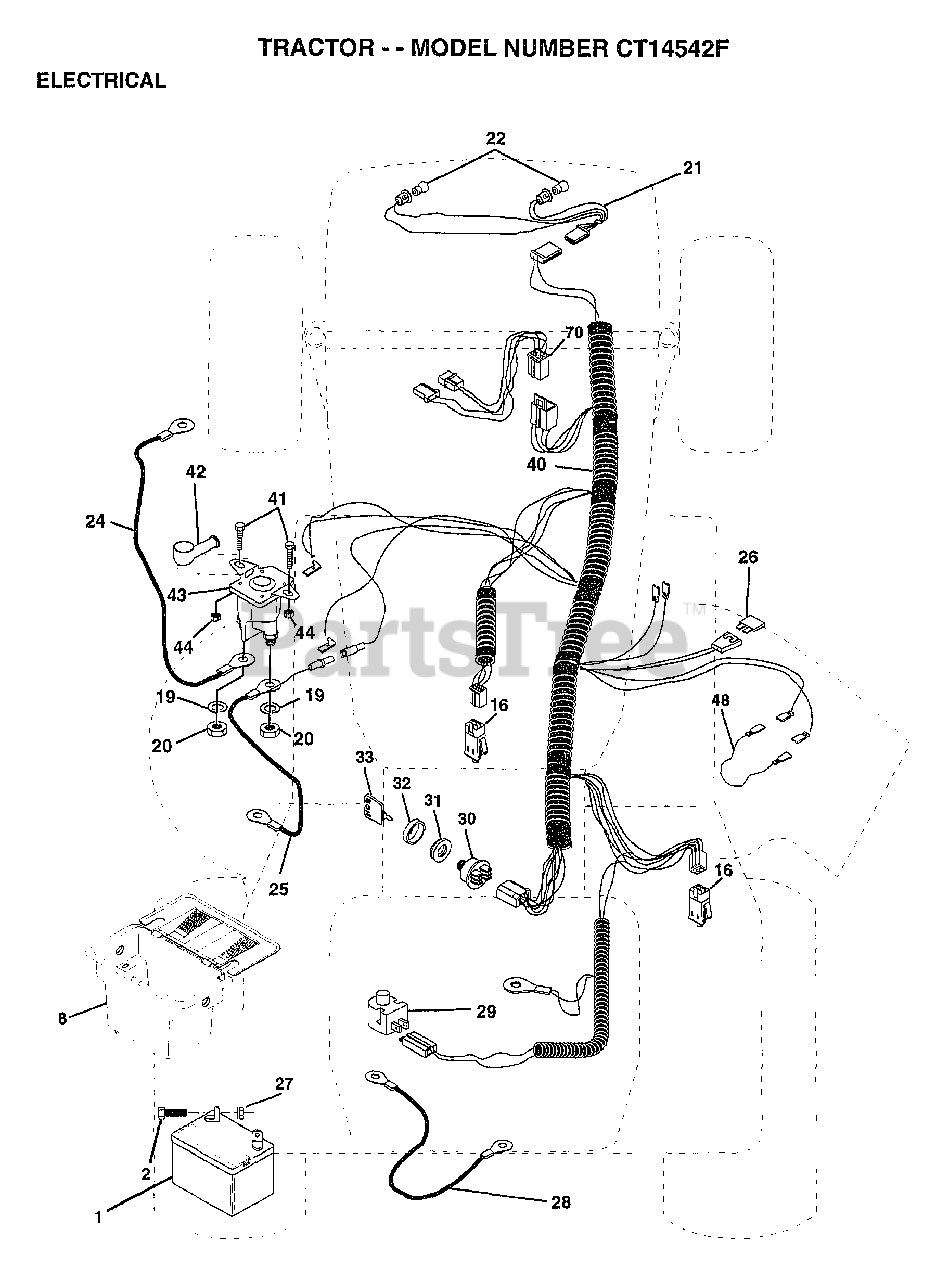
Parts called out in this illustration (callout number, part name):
2	BOLT LT
8	"CASE,BATTERY.MECH"
16	SWITCH INTERLOCK
20	NUT
21	"HARNESS,LIGHT SOC"
22	HEADLAMP BULB
24	CABLE.BTRY.6GA.RD
25	CABLE.BTRY.6GA.38
26	FUSE HYT
27	NUT
28	CABLE T
29	SWITCH SEAT
30	SWITCH IGN 4POS
31	NUT IGNITION
32	COVER KEY SWITCH
33	KEY
40	HARNESS IGNITION
41	BOLT HXHD FIN
44	NUT HXKEP 1/4X20
48	ADAPTER AMMETER
70	HARNESS.ENG.DUAL
